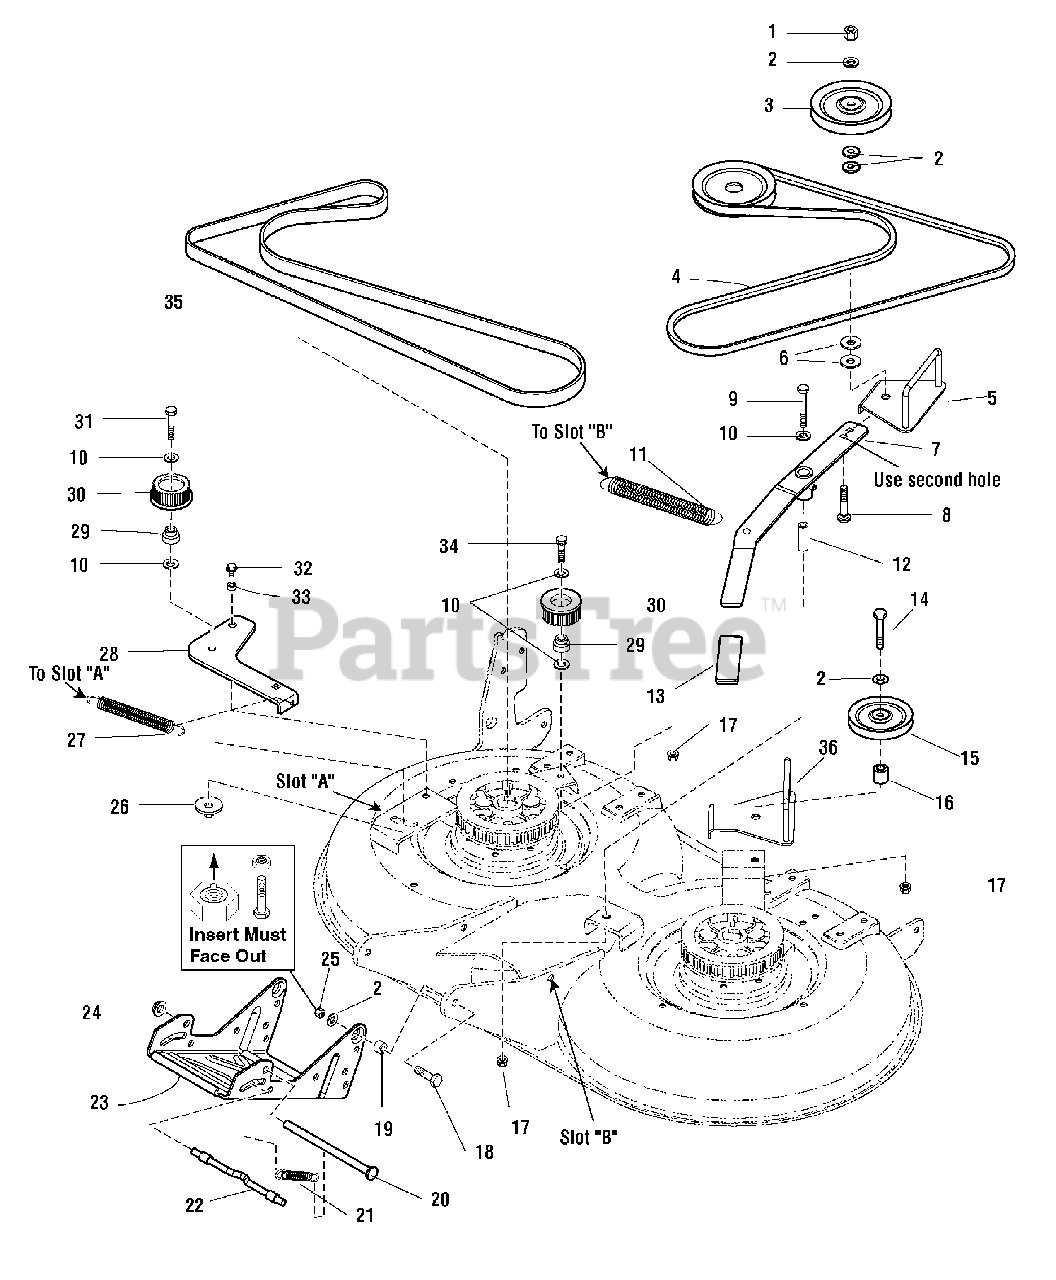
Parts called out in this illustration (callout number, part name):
1	NUT, Hex Lock Esna Light, 3/8-16
2	WASHER, 3/8
3	PULLEY, Idler, 4" O.D.
4	V-BELT, Arbor Drive
6	WASHER, 3/8
7	ARM ASSEMBLY, Idler with Bushings & Fitting
8	CARRIAGE BOLT, 3/8-16 x 2-1/2
9	CAPSCREW, Hex Head, 3/8-16 x 2-3/4 G8
10	WASHER, 3/8
11	SPRING, Extension
12	SPACER, Hardened
13	GRIP, Black Vinyl for Handle
14	CAPSCREW, Hex Head, 3/8-16 x 2-1/4
15	PULLEY, Idler, 4" O.D.
17	NUT, Hex Flange Whiz Lock, Large, 3/8-16
18	CAPSCREW, Hex Head, 3/8-16 x 1-1/2
20	ROD, Mower Hitch
21	SPRING, Extension
23	HITCH, Mower
24	NUT, Push
25	NUT, Hex Lock ALUM Insert, 3/8-16
26	WASHER & NUT ASSEMBLY, 3/8 x 1-1/2
27	SPRING, Extension
28	ARM, Idler
30	PULLEY, Idler, 22 Teeth
31	CAPSCREW, Hex Head, 3/8-16 x 2
32	CAPSCREW, Taptite Hex Washer Head, 5/16-18 x 1/2
34	CAPSCREW, Hex Head, 3/8-16 x 1-3/4
35	BELT, Timing
